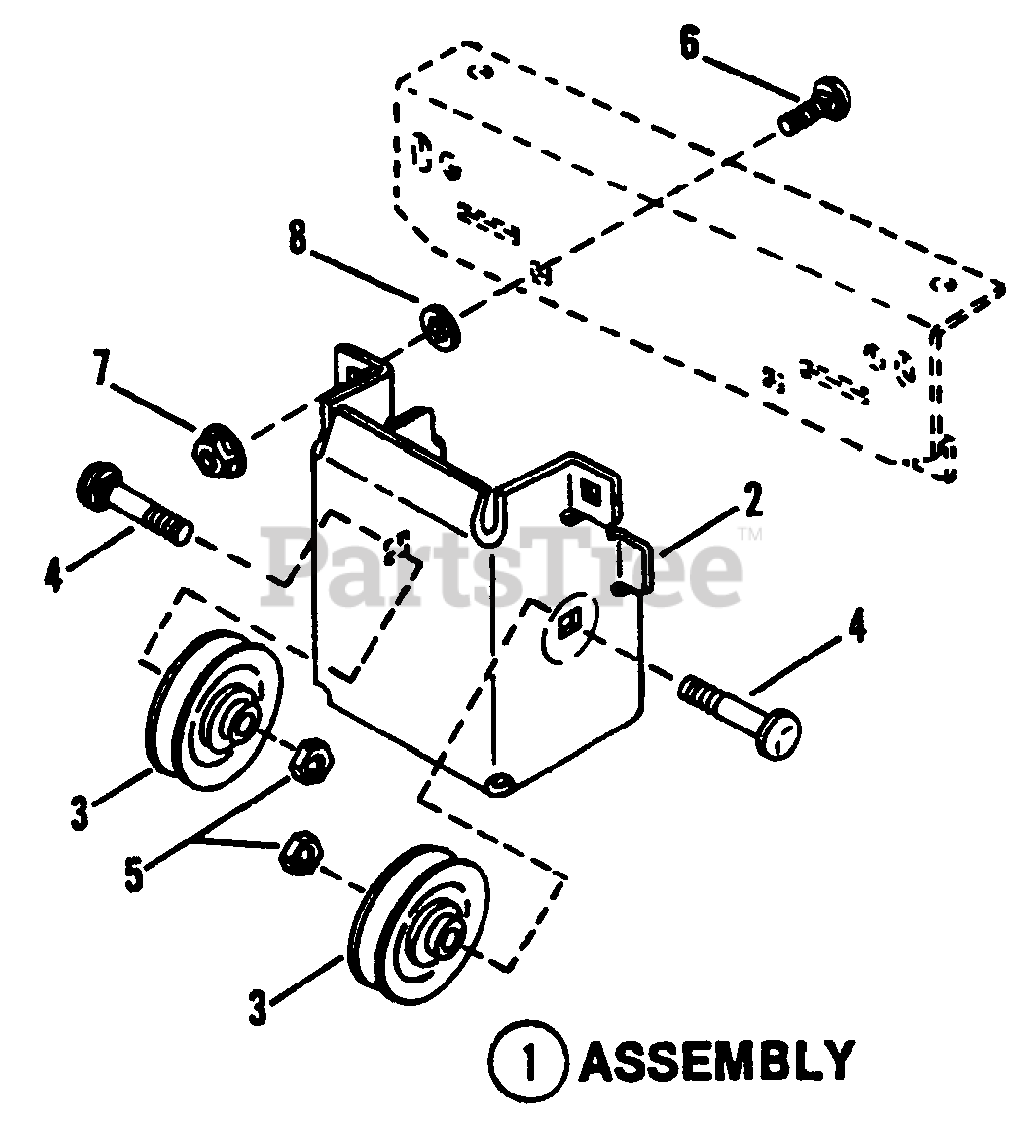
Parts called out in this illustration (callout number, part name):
1	ASSEMBLY, Mule Drive
2	BRACKET, Mule Drive
3	PULLEY, Belt Idler
4	BOLT, 3/8-16 x 1-1/2" Short Square Neck Carriage, Grade 5
5	NUT, 3/8-16 Hex Top Lock
6	BOLT, 3/8-16 x 3/4" Square Neck Carriage, Grade 2
7	NUT, 3/8-16 Hex Flange Lock
8	RETAINER, 3/8 Bolt
